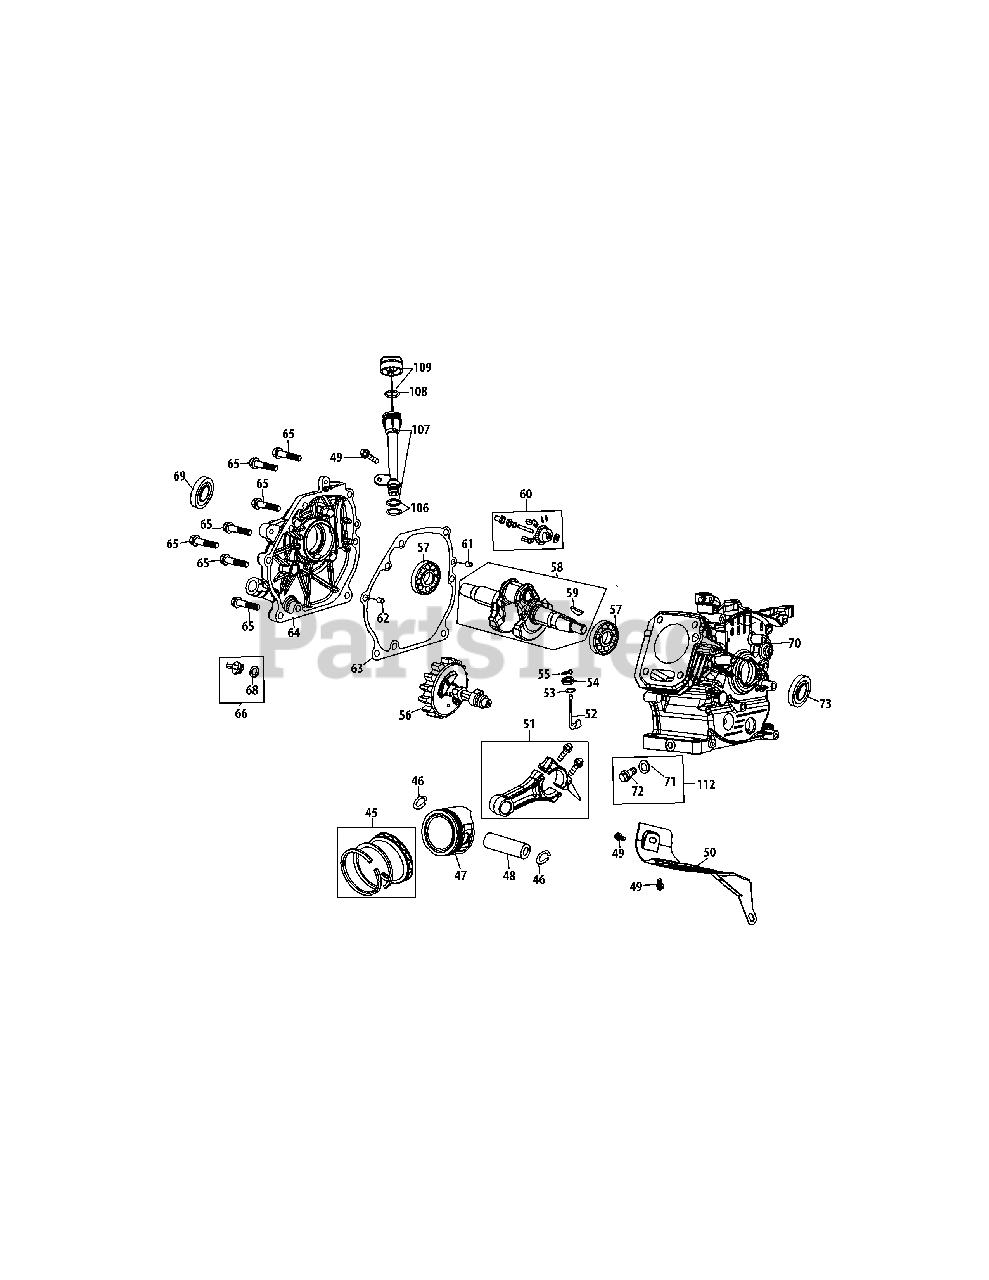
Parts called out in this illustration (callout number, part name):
45	Piston Ring Set
46	Piston Pin Snap Ring
47	Piston
48	Piston Pin
49	Bolt M6×12
50	Air Shield
51	Connecting Rod Assembly
52	Governor Arm Shaft
53	Washer 5.2×1.9
54	Governor Seal
55	Cotter Pin
56	Camshaft Assy.
57	Radial Ball Bearing, 6205
58	Crankshaft Kit
59	Woodruff Key
60	Governor Gear/Shaft Assembly
61	Dowel Pin 7×14
62	Dowel Pin 9×14
63	Crankcase Cover Gasket
64	Crankcase Cover Kit
65	Bolt M8×32
66	Oil Fill Plug Assembly
68	O-Ring 15.8×2.5
69	Oil Seal, 25×41.25×6
70	Crankcase Kit
71	Washer 10×16×1.5
72	Oil Drain Bolt
73	Oil Seal 25×41.25×6
106	Oil Fill Tube O-Ring
107	Oil Fill Tube Assembly
108	Dipstick O-Ring
109	Dipstick Assembly
112	Oil Drain Assembly
